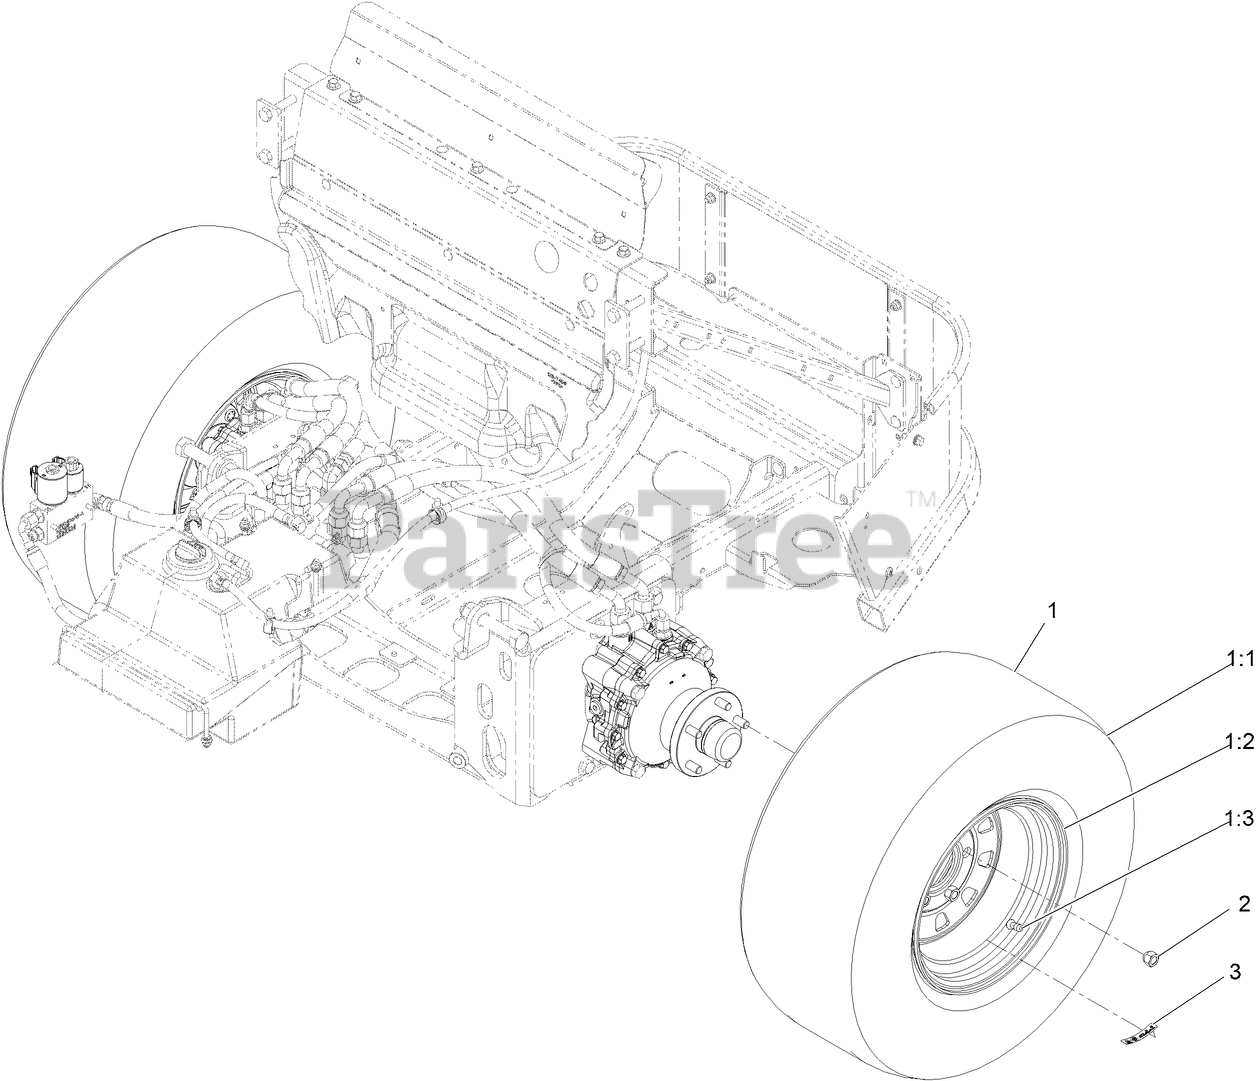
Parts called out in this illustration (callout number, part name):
1	ASM-TIRE 26 X 12-12
1:1	RIM ASM
1:3	Stem-Valve
2	NUT-LUG
3	DECAL-TORQUE, WHEEL NUT
